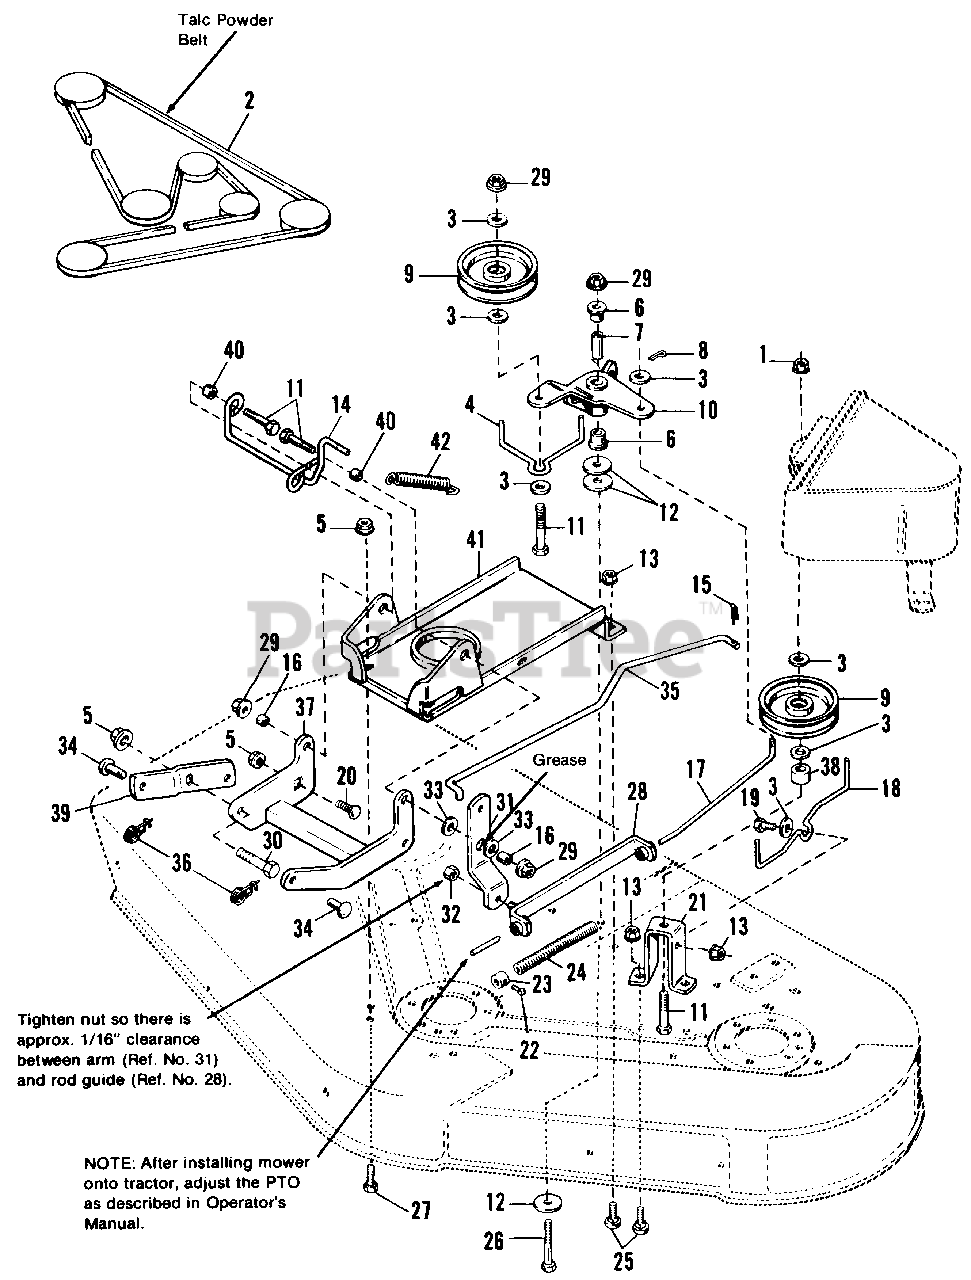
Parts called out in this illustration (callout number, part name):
1	NUT, Hex, Full, Flange Whizlock, 3/8-16
2	V-BELT, Mower Drive (42" only)
2	V-BELT, Mower Drive, Kevlar (48" only)
3	WASHER, Plain
5	NUT, Flange, Whizlock, 7/16-14
8	PIN, Cotter, 3/32 x 3/4
9	PULLEY, Idler
10	LEVER ASSY., Clutch
11	CAPSCREW, 3/8-16 x 1-3/4
12	WASHER, Special
13	NUT, Hex, Flange Whizlock, 5/16-18
14	ROD, Brake (42" only)
14	ROD, Brake (48" Only)
15	PIN, Quick, 1-7/8
17	ROD, Clutch, Mower
19	CAPSCREW, Hex, 5/16-18 x 1
20	CARRIAGE BOLT, 7/16-14 x 1-1/4
21	SUPPORT, Idler
22	SETSCREW, Sq. Hd., 1/4-20 x 3/8
23	COLLAR, Set
25	BOLT, Carriage, 5/16-18 x 3/4
26	CAPSCREW, 3/8-16 x 2-3/4
27	BOLT, Whizlock, 7/16-14 UNC x 1"
28	GUIDE ASSY., Rod
29	NUT, Hex, Flange, 3/8-16
30	CAPSCREW, Hex Hd., 7/16-14 x 1-1/4
31	ARM, Pivot
32	NUT, Jam, Ctr. Lock, 5/16-18
33	WASHER, Plain, 5/8
35	ROD, Clutch, Tractor, P.T.O.
36	PIN, Safety
37	ARM ASSY., Rocker
39	ARM, Rocker
41	SUPPORT ASSY.
42	SPRING, Tension
